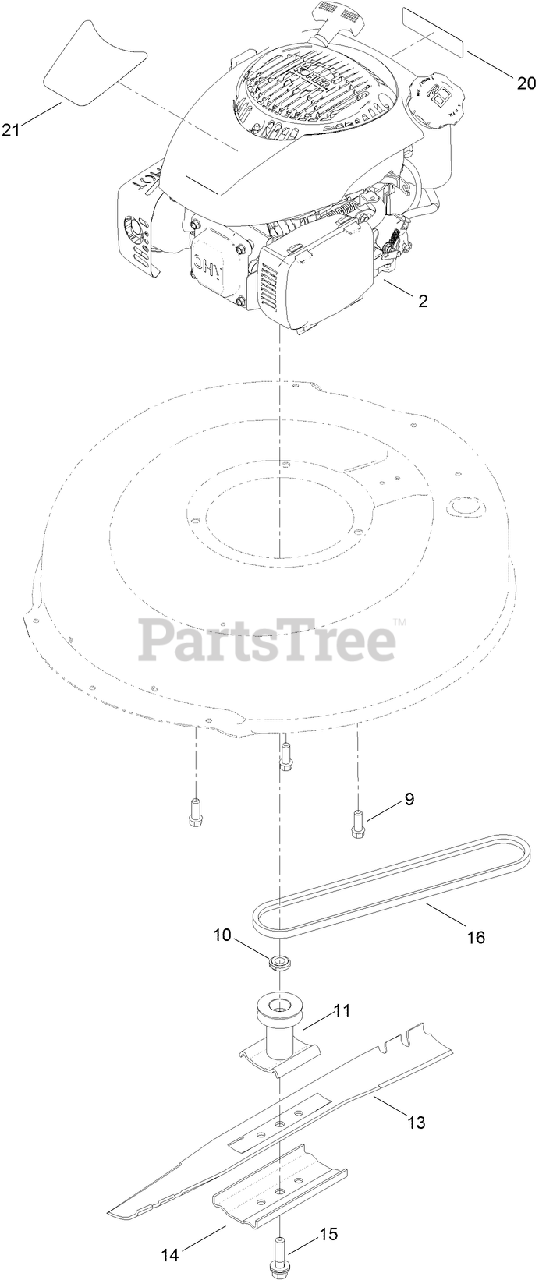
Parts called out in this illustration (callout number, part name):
9	SCREW-TAPTITE
10	SPACER-DRIVER
11	DRIVER-BLADE
14	SUPPORT-BLADE
15	BOLT-BLADE
20	DECAL-ARRESTER, SPARK
